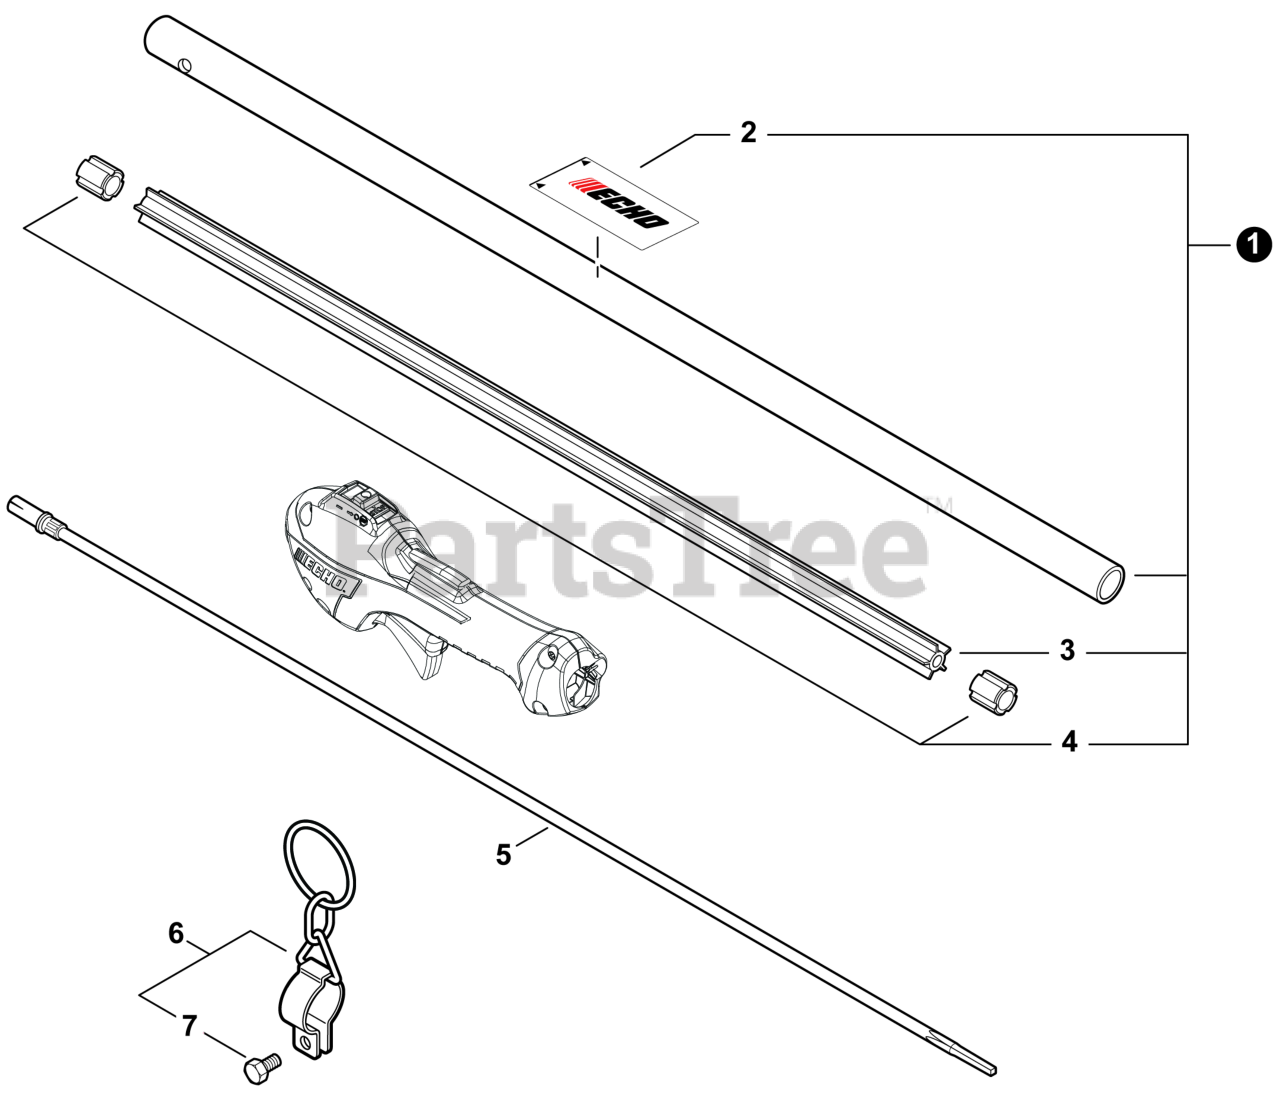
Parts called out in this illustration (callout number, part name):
1	MAIN PIPE ASSY
2	LABEL - HANDLE LOCATION
3	LINER - FLEXIBLE
4	STOPPER
5	DRIVESHAFT - FLEXIBLE
6	HANGER SET, HARNESS
7	BOLT, TORX 5x12
